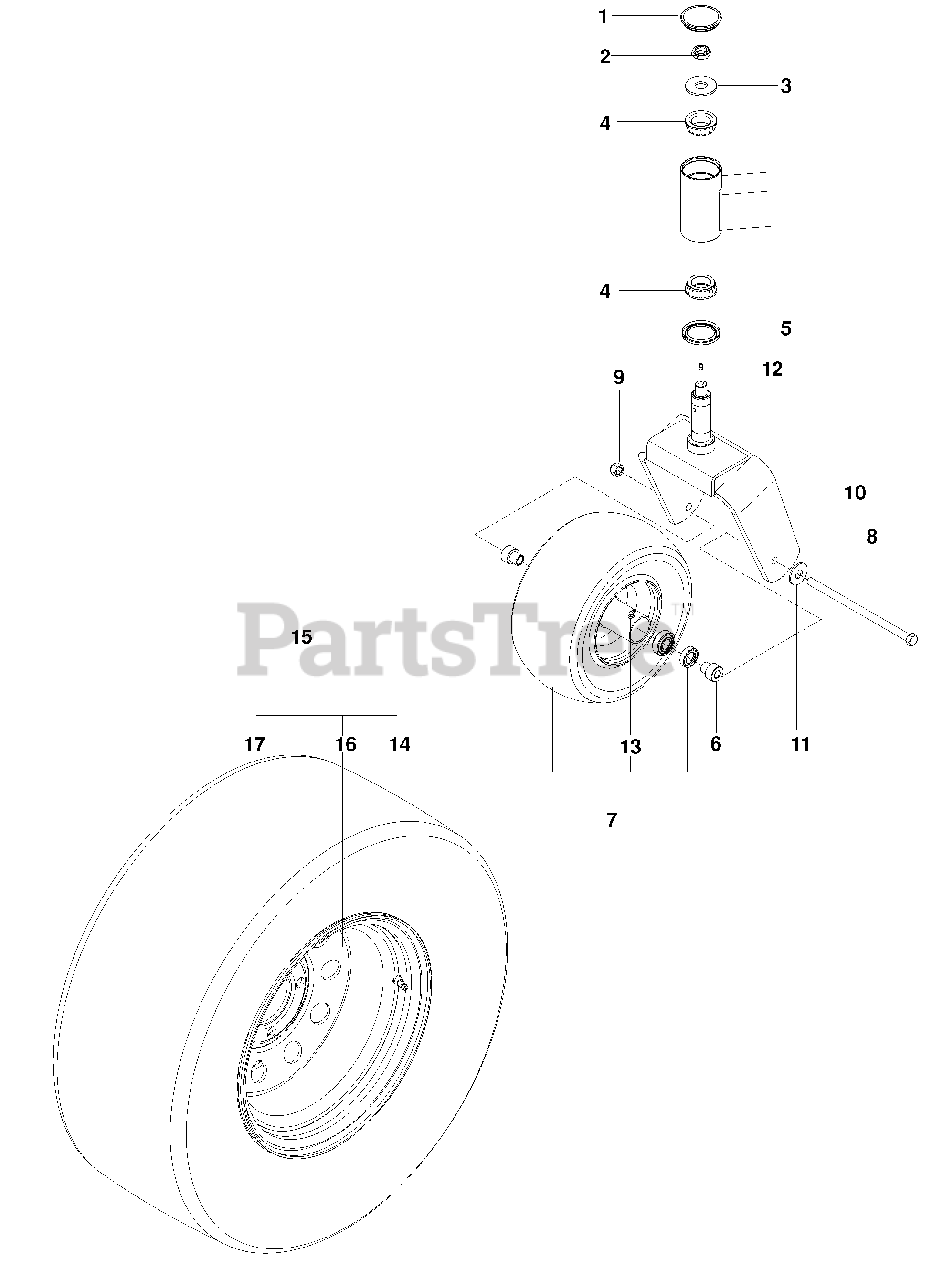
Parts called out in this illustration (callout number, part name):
2	Nut 3/4-16 Hex Thin Nyloc
3	Washer 3/4 Hardened
4	Bearing, Tapered
5	Seal, Bearing
6	Axle Spacer
7	Tire Assy 13 X 6.5, Flt Free
8	Bolt 1/2-13 X 9 1/2 Hex Nyloc
9	Nut 1/2-13 Hex Flg Nyloc
10	Fork, Caster Org
11	Washer 1/2 Sae
13	Zerk
14	Stem, Valve
15	Wheel Assy
16	Rim 12 X 8.5 Centered
17	Tire 26 X 12-12
